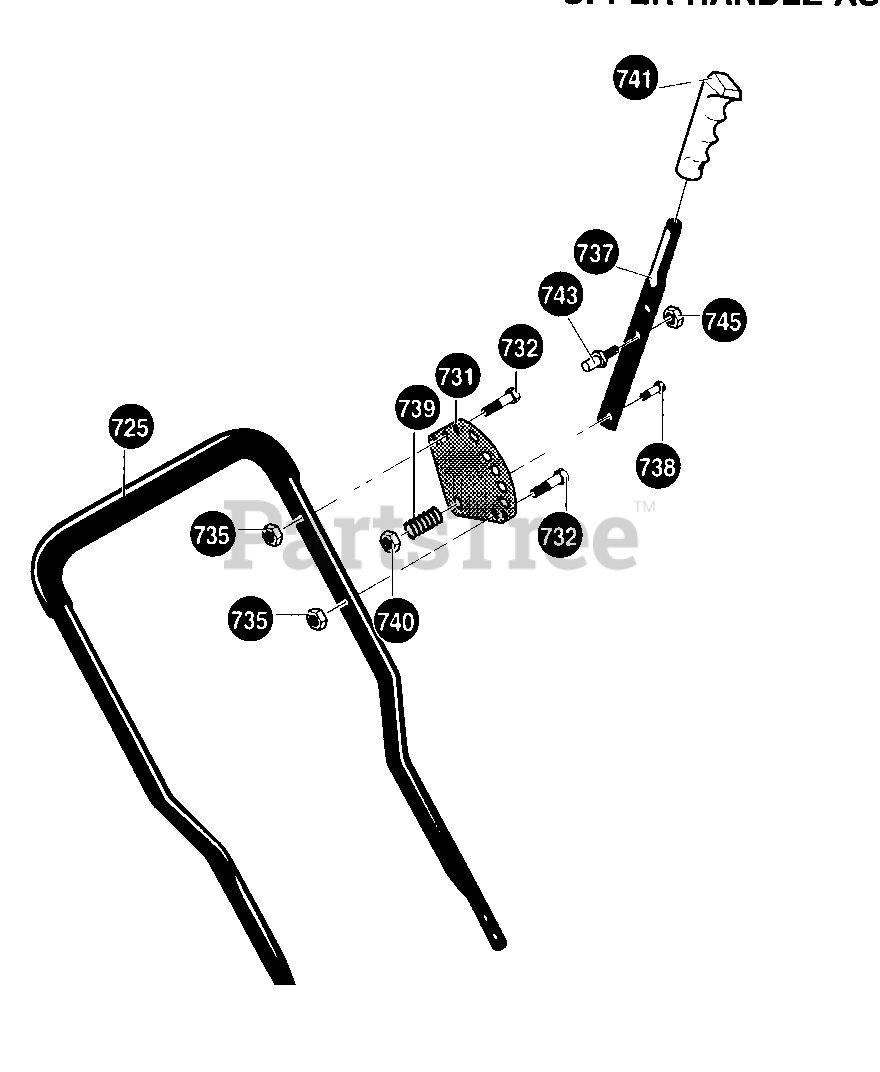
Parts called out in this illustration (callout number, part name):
725	Upper Handle & Foam
731	Plate Selector
732	Screw, 1/4-20 x 1.25
735	Nut, 1/4-20 Reghexctrlk
737	Handle, Depth Adjust
738	Screw, 5/16-18 x 1.25
740	Nut, 5/16-18 Reghexctrlk
741	Grip, Hand
745	Nut, 3/8-16 Reghexctrlk
